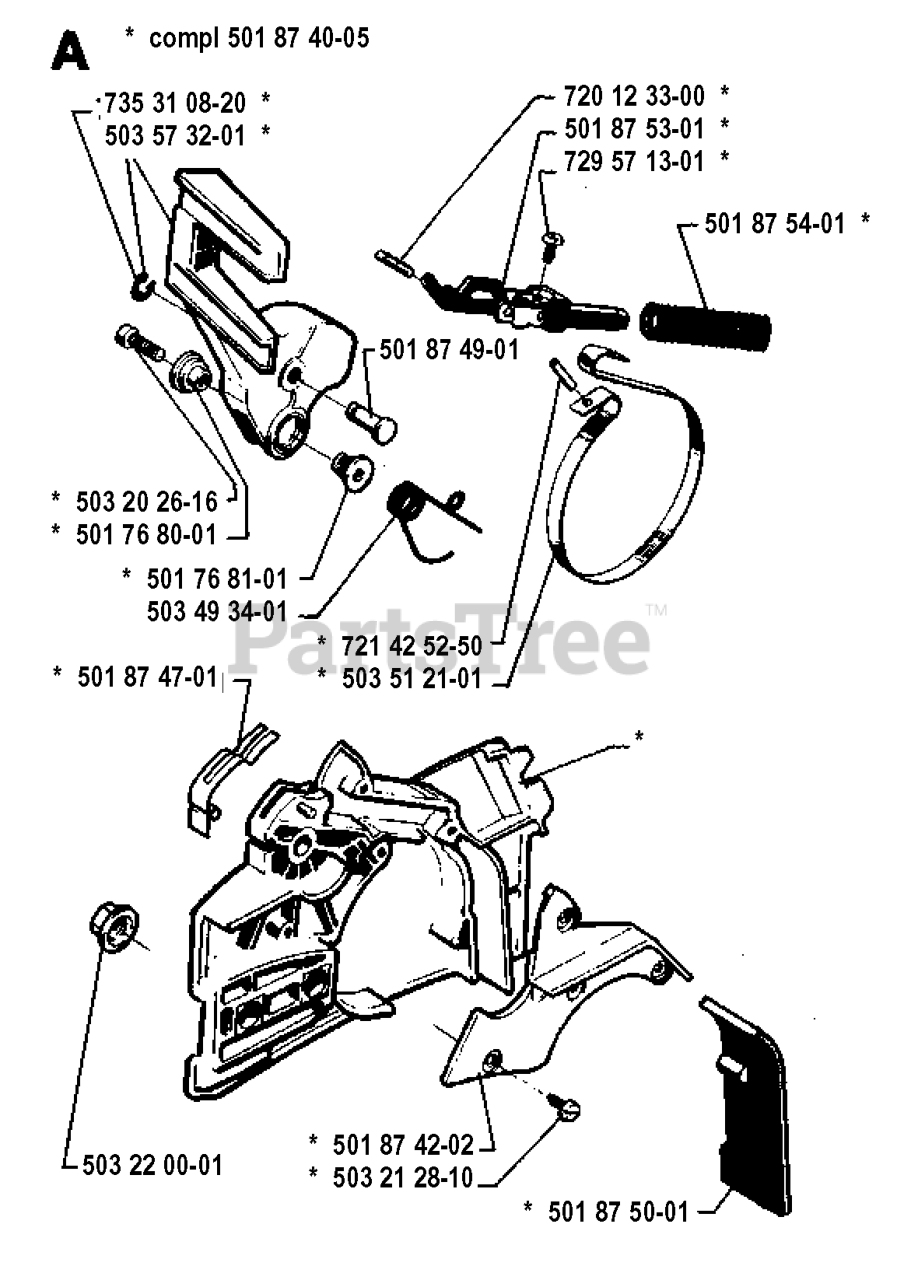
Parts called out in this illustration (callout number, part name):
1	SEAT.TH151.GREY.PREM.HUSQ.MI
2	BRKT.PIVOT.FENDER
3	STRAP
6	NUT
7	SPRING COMPRESSION
8	BOLT.5/16-18UNCX3/4 W/SEMS.BLK
10	PAN.ASM.SEAT.3PT
21	BOLT.SHOULDER.5/16-18
37	NUT.71038.31-18.HEX.NYLOCK
40	HANDLE.SLIDE.SEAT.TEX.BLACK
41	SPRING.LATCH.SEAT.TEX
44	WASHER 13/32 X 2-3/8 X 12GA
